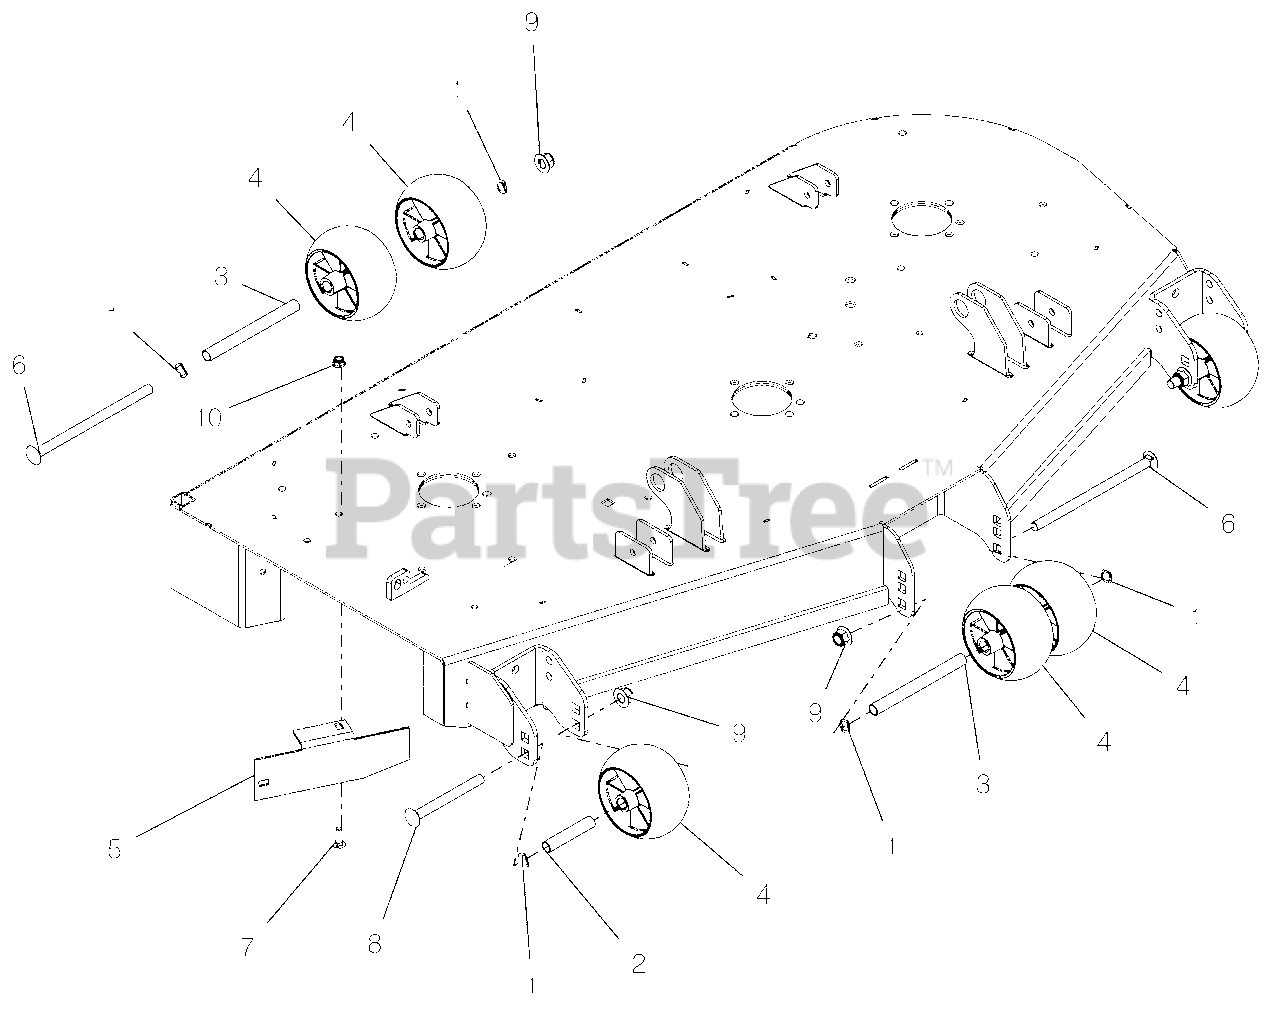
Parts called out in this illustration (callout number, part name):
1	WAVE WASHER .531X.781X.125FH
2	SPACER, .510X.625X3.35
3	SPACER, .510X.625X6.50
4	ANTI-SCALP WHEEL - 5X3 CTR
5	BAFFLE, DISCHARGE, 52"
6	@BLT-RDHDSQNK .50-13X8.50 G5YZ
7	@BLT-RDHDSQNK .31-18X1.00 G5YZ
8	BLT-RDHDSQNK .50-13X5.00 GR5YZ
9	@NUT-LK-NYL-FLG .50-13 YWZC
10	@NUT-LK-NYL-FLG .31-18 YWZC
